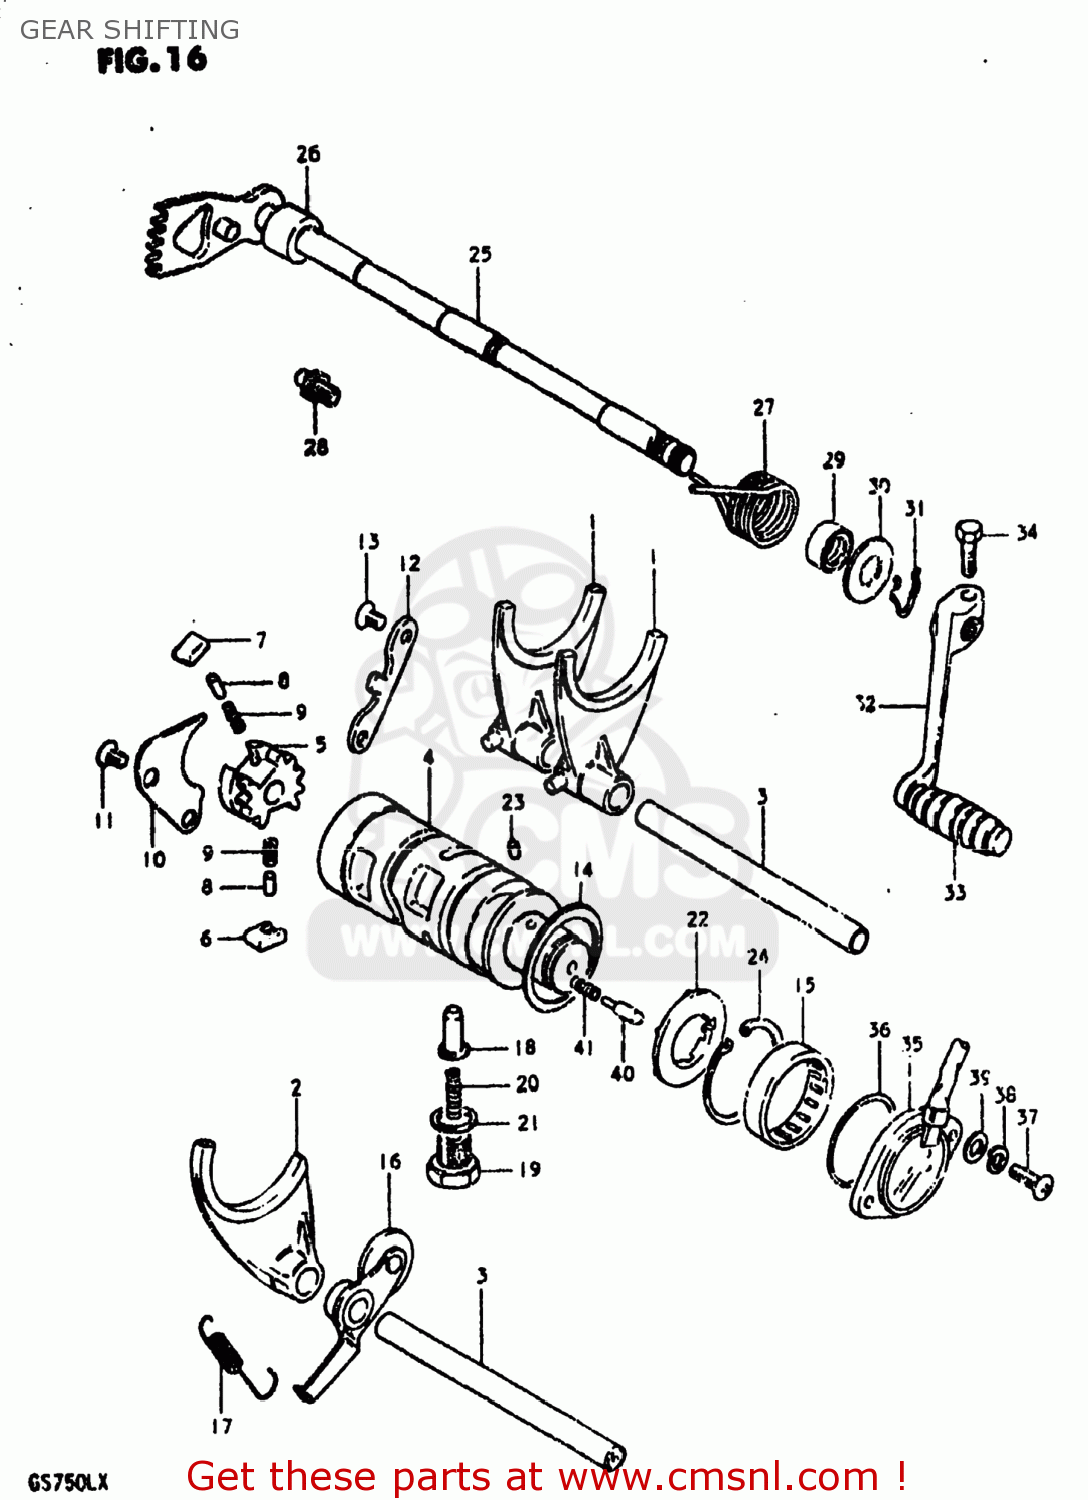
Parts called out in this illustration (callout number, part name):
1	FORK,GEAR SHIFT NO.1
2	FORK,GEAR SHIFT NO.3
3	SHAFT,GEAR SHIFT FORK
4	CAM,GEAR SHIFT
5	RETAINER,GEAR SHIFT CAM
6	PAWL,GEAR SHIFT NO.1
7	PAWL,GEAR SHIFT NO.2
8	PIN(5X8)
9	SPRING
10	LIFTER,GEAR SHIFT PAWL
11	SCREW
12	GUIDE,GEAR SHIFT CAM
13	SCREW
14	WASHER(40X45X1)
15	BEARING(25X32X12)
16	STOPPER,GEAR SHIFTING
17	SPRING
18	STOPPER,GEAR SHIFT CAM NO.2
19	HOLDER,GEAR SHIFT CAM STOP SPR
20	SPRING
21	GASKET(14X19.2X2) (NAS)
22	PLATE,GEAR SHIFT CAM STOPPER
23	PIN 4X6
24	CIRCLIP
25	SHAFT,GEAR SHIFT
26	SPACER(12X20X15.3)
27	SPRING
28	STOPPER,GEAR SHIFT CAM
29	OIL SEAL
30	WASHER (12.5X27X1.6)
31	SPRING,RETAINER
32	LEVER ASSEMBLY,GEAR SHIFTING
33	RUBBER,GEAR SHIFT PEDAL
34	BOLT
35	TERMINAL BASE ASSY,GEAR SHIFT
36	O-RING (D:2.4 ID:26.2)
37	SCREW 5X20
38	LOCK WASHER
39	WASHER
40	PIN(5X15.5)
41	SPRING
